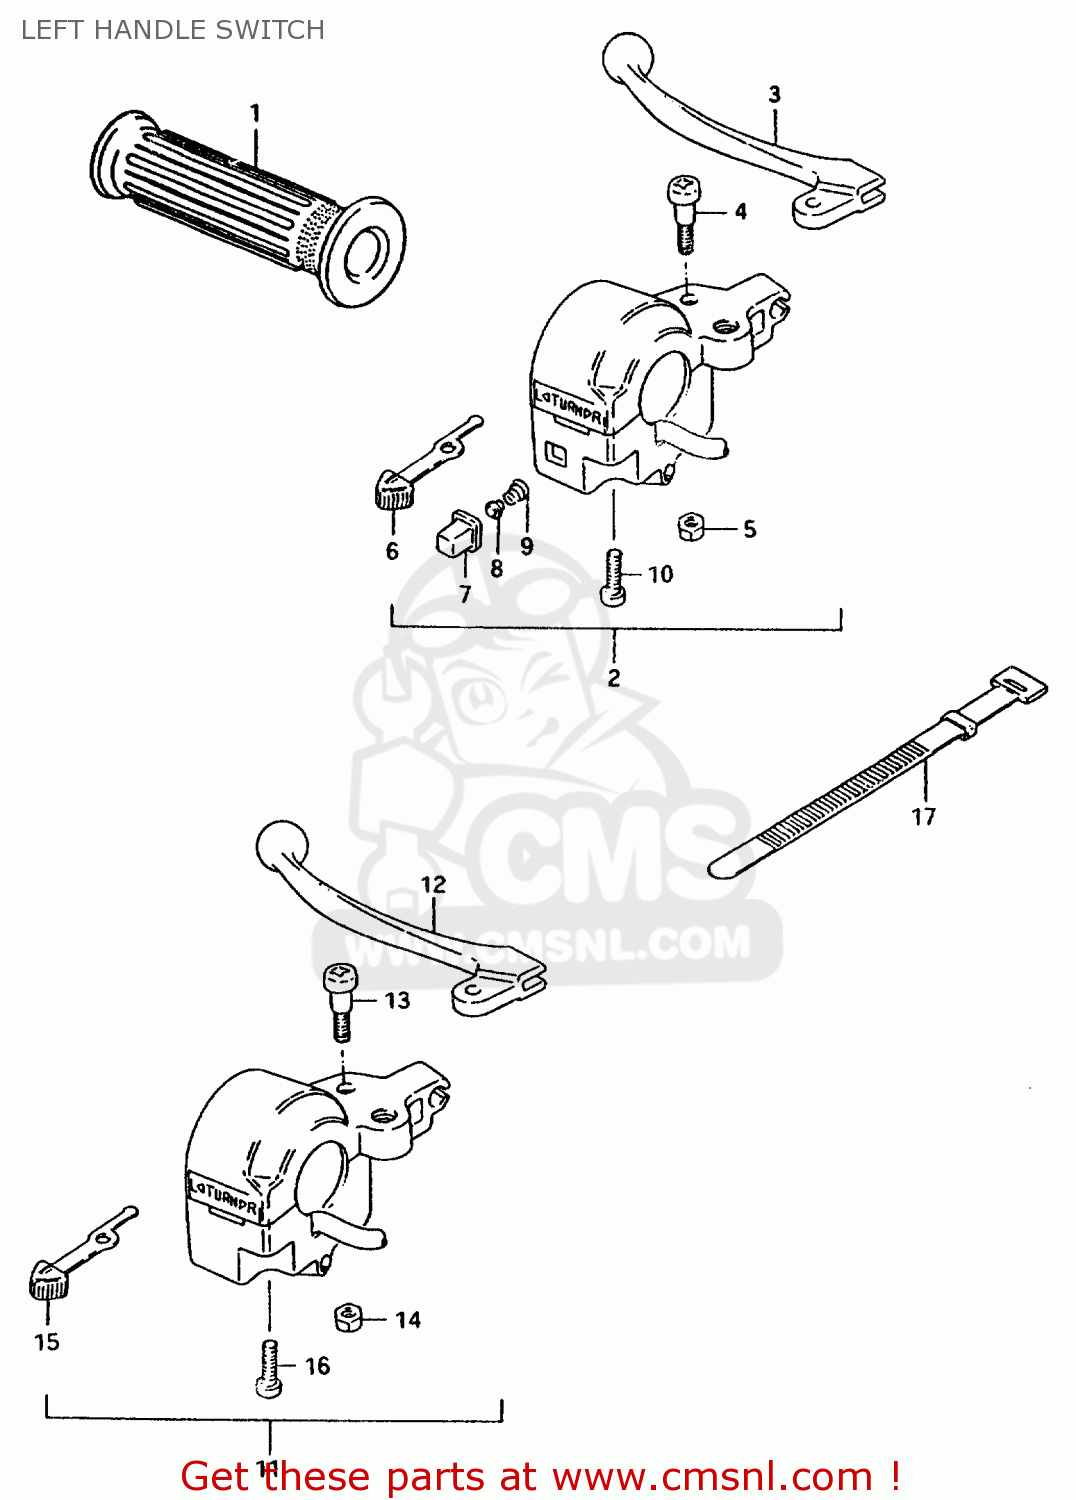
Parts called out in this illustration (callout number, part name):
1	GRIP,L
2	CLUTCH LEVER ASSY
3	LEVER
4	BOLT,LEVER
5	NUT,LEVER BOLT
6	KNOB,TURN SIGNAL SWITCH
7	BUTTON,HORN
8	CONTACT
9	SPRING
10	SCREW 5X20
11	CLUTCH LEVER ASSY
12	LEVER
13	BOLT,LEVER
14	NUT,LEVER BOLT
15	KNOB,TURN SIGNAL SWITCH
16	SCREW 5X20
17	CLAMP(L:120)
